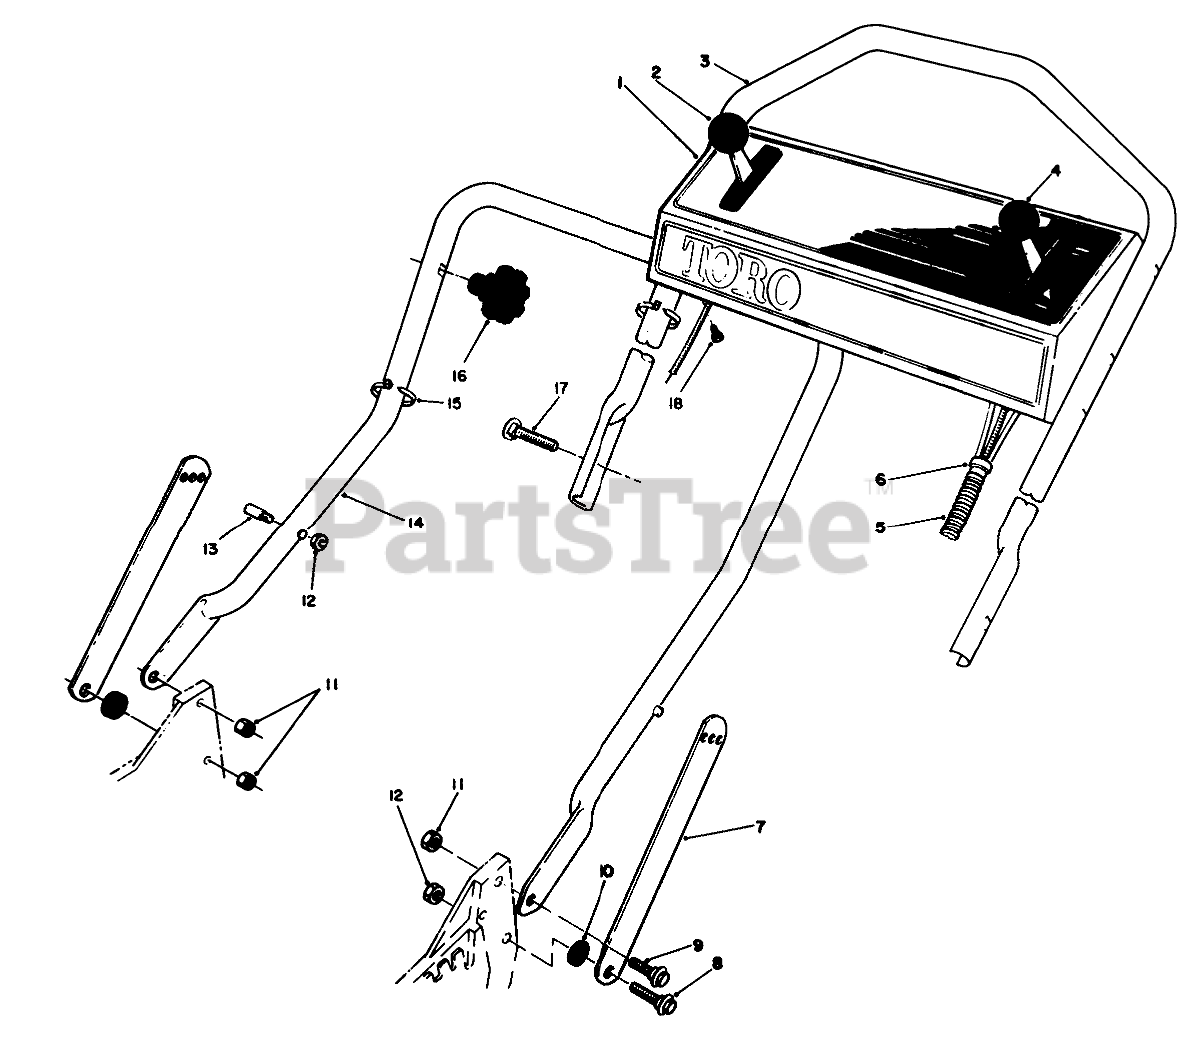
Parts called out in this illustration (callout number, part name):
1	Panel-Control
2	GROUND SPEED CONTROL
3	Handle-Upper
4	Control-Throttle (Bend #5)(Sheath 4. 55-7/8 inches)(Wire 4. 2-1/2 inches)
5	CONTROL CABLE COVER
6	FITTING-RING
7	Handle Latch
8	SCREW-SHOULDER
9	SCREW-SHOULDER
10	SPACER
11	NUT-LOCK, NI
12	NUT-LOCK, NI
13	HANDLE PIN
14	LOWER HANDLE ASM
15	TIE-CABLE
17	5/16-18 X 2 HNDLE SCREW
18	SCREW-HWHTF
